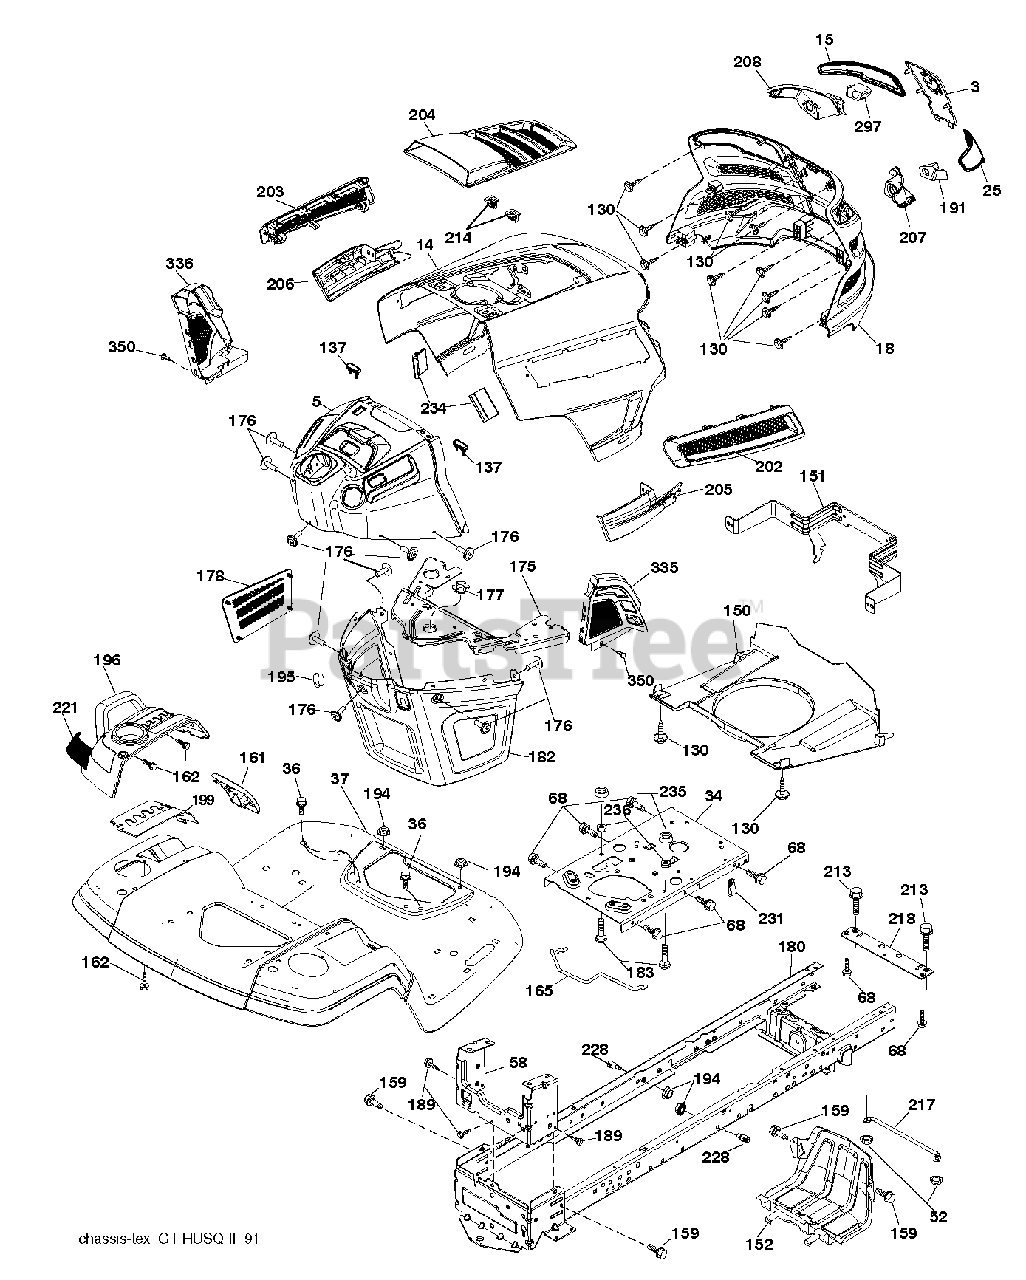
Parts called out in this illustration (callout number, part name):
3	APPLIQUE.SUBASM.GT.HUSQ.II
5	DASH.UPP.GT2.SM.PTO.MCHOKE
14	HOOD.ASM.HUSQVARNA.GT.TEX.ORAN
15	LENS.HEADLIGHT.LH.GTII.2011
18	GRILLE.SUBASM.GT.HUSQ.II
25	LENS.HEADLIGHT.RH.GTII.2011
34	PLATE.ENGINE.WELDED.CHASSIS
36	SCREW 5/16"
37	FENDER.PNT.TX.GT.CH/FW/DL.HUSQ
52	LOCKNUT
58	DRAWBAR.UPPER.2PC,LRG.FENDER
68	SCREW LT
130	SCREW.#10 X 0.750.BOS
137	BUMPER DASH
150	AIR.DUCT.GTV.BLACK
151	BRACKET.PIVOT.HOOD.GT.HUSQ.II
152	SHIELD.BROWNING.PNT.GT.V2
159	SCREW, 3/8-16X3/4
161	CONSOLE.WINDOW.FUEL.HUSQ.GT
162	SCREW.HI-LO.CONSOLE
165	SUPPORT.TANK.REAR.W/TEX
175	PLATE.CROSSMEMBER.HUSQ
176	SCREW.#10-24X5/8.RN.QU
177	BUSHING, STEERING
178	CARGO.ASM.NET.TXGT.W/C
180	CHASS.WLDMNT.TLT.12GA/2PC.20"
182	DASH.LOWER.COMMON.12V.ADAPTOR
183	BOLT.5/16-18X1-1/4 FULL THD
189	SCREW
191	INSERT.REFLECTIVE.RH.HUSQ.GTII
194	NUT LOCK HEX FLANGE 5/16-18
195	PLUG.HOLE.DASH.LOWER.12V.BLK
196	SUBASM.CONSOLE.HUSQ.GT.DECKLFT
199	PLATE.DECK.LIFT.HUSQVARNA.GT
202	VENT.SIDE.RH.GT.HUSQ.II.
203	VENT.SIDE.LH.GT.HUSQ.II.498
204	VENT.TOP.HUSQ.GT2
205	SIDE.TRIM.RH.GT.HUSQ.II
206	SIDE.TRIM.LH.GT.HUSQ.II.GRAY
207	BEZEL LIGHT.RH.GT.II.MYLAR
208	BEZEL LIGHT.LH.GT.II.MYLAR
213	BOLT
214	CLIP.RETAINER.TINNER.
217	ROD.PIVOT.HOOD
218	X-PIECE.HOOD.STOP.NON/
221	REFLECTOR.LH.TEX GT HU
228	STUD.FASTNER.W/ANTI-ROTATE
231	CLIP RETAINER
234	BUMPER.HOOD.TEX.HUSQVARNA
235	SPACER FENDER
236	NUT.CENTERLOCK.5/16-
297	INSERT.REFLECTIVE.LH.HUSQ.GTII
335	COVER.LOWER.DASH.RH.BLACK
336	COVER-LH.LOWER.DASH.GT2.BLACK
350	CLIP.X-MAS.TREE
